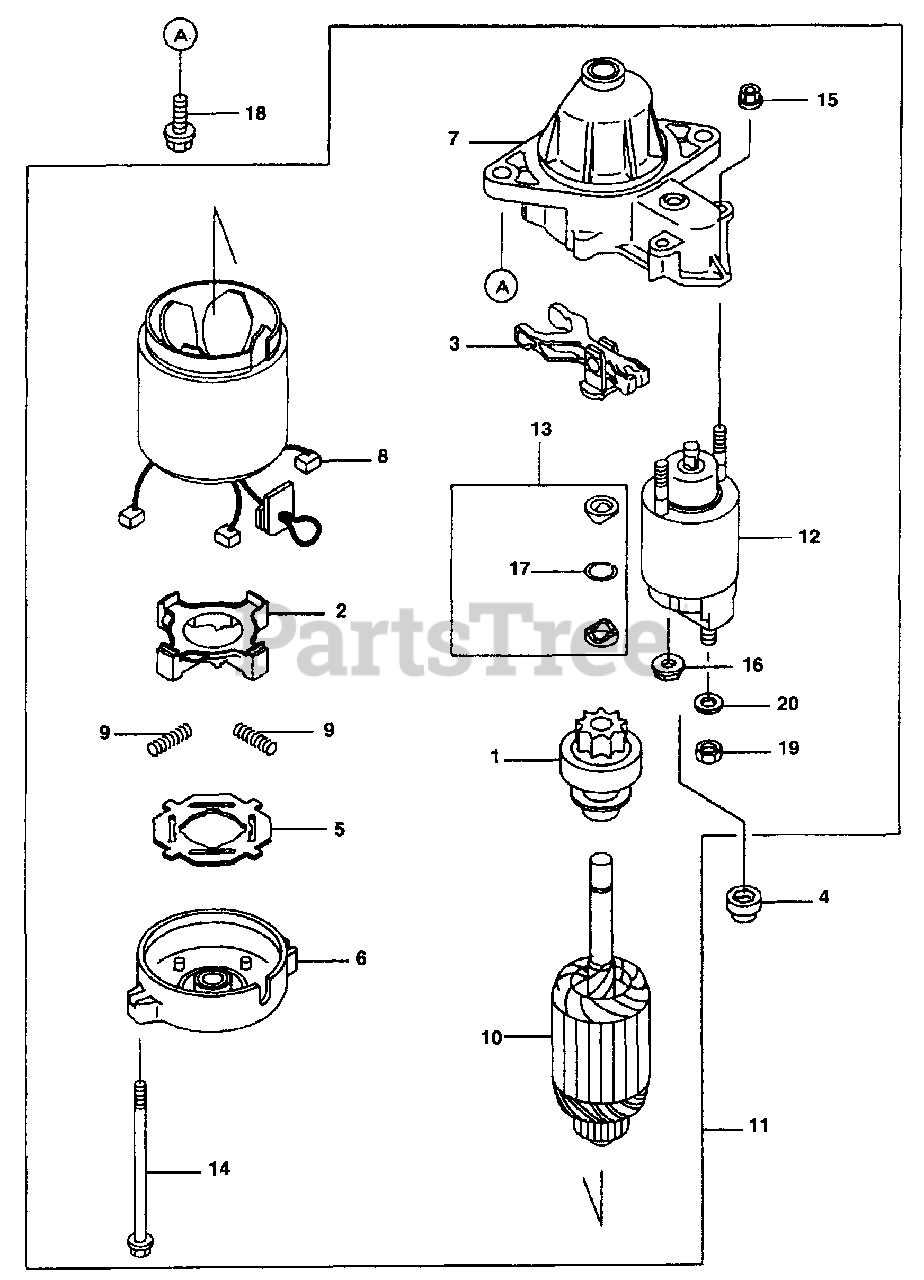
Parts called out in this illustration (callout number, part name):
11	Electric Starter
12	Switch
18	Flanged Bolt
19	Small Hex Nut
20	Spring Washer
